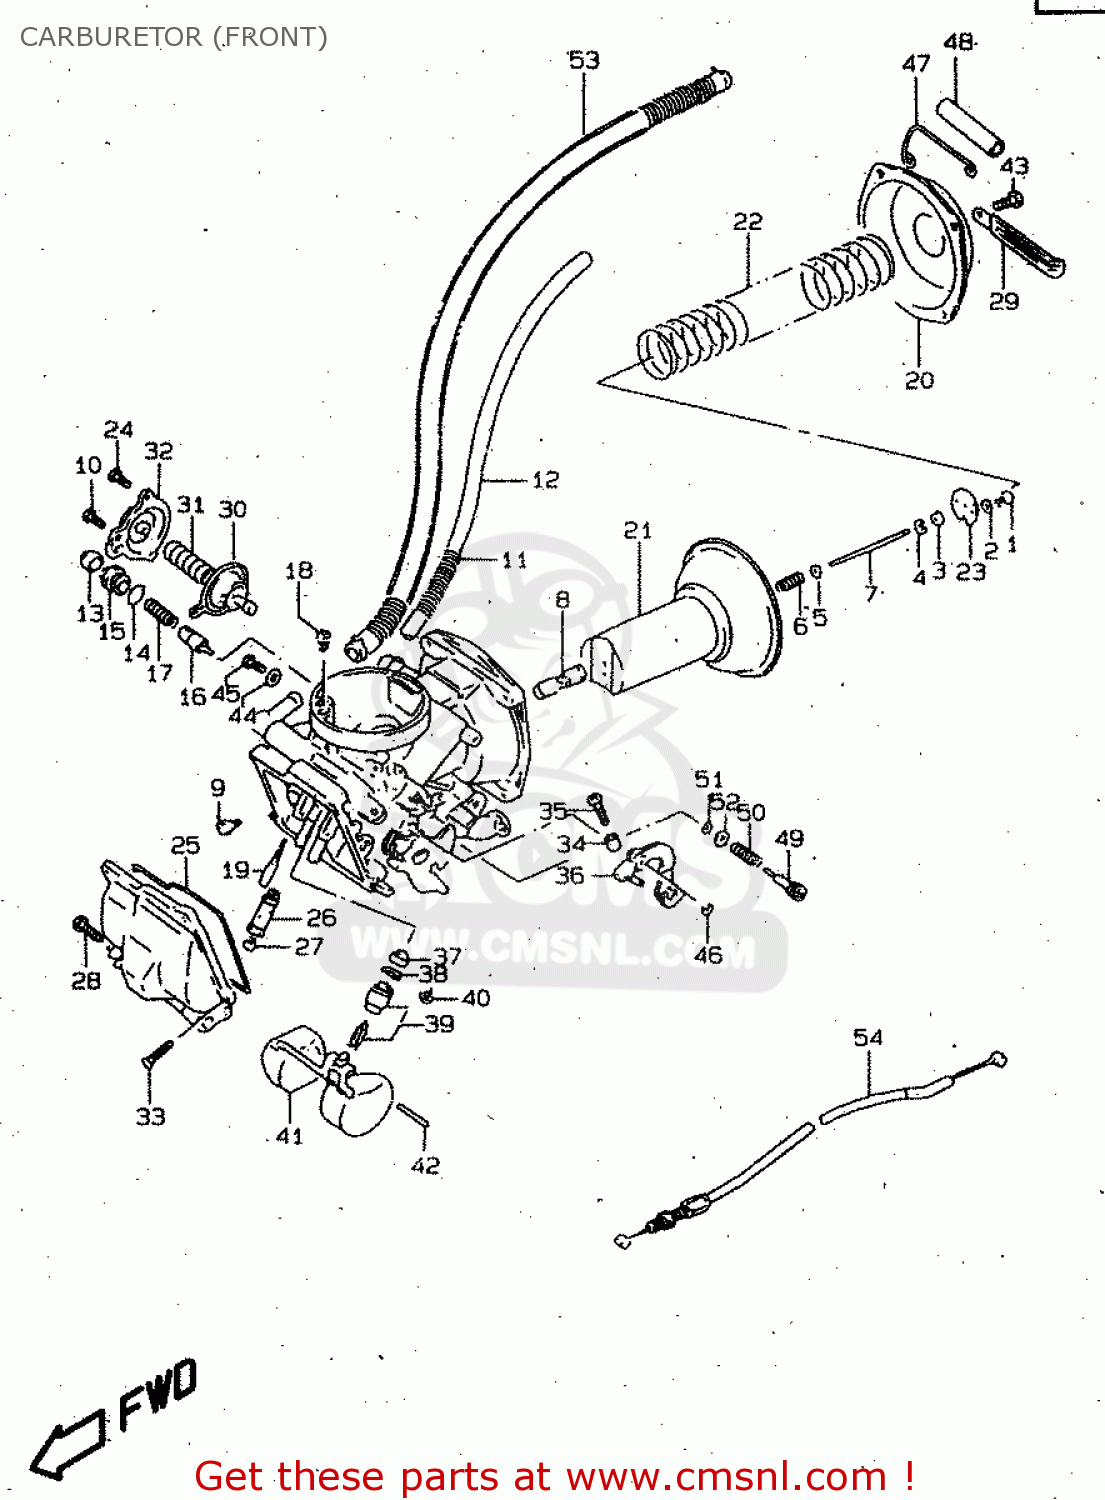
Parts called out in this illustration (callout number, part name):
1	SCREW
2	WASHER,LOCK
3	RING
4	CLIP
5	WASHER
6	SPRING
7	NEEDLE,JET
8	JET,NEEDLE(P-4)
9	SCREW
10	SCREW
11	SPRING
12	HOSE(5X8.2X600)
13	CAP
14	O RING
15	HOLDER,GUIDE
16	PLUNGER,STARTER
17	SPRING
18	JET,AIR(65)
19	JET,PILOT(40)
20	COVER
21	DIAPHRAGM ASSY
22	SPRING,DIAPHRAGM
23	PLATE
24	SCREW,UPPER
25	O RING,FLOAT CHAMBER
26	HOLDER,MAIN JET
27	JET,MAIN(95)
28	SCREW,DRAIN
29	CLAMP(L:65)
30	DIAPHRAGM ASSY
31	SPRING
32	COVER
33	SCREW
34	NUT
35	SCREW
36	LEVER ASSY
37	FILTER
38	O-RING,NEEDLE VALVE
39	VALVE ASSY,NEEDLE
40	SCREW
41	FLOAT
42	PIN,FLOAT
43	SCREW
44	GASKET,DRAIN PLUG (NAS)
45	SCREW(5X6)
46	E RING
47	CLIP
48	HOSE(6X10X600)
49	SCREW,PILOT
50	SPRING
51	O RING,PILOT AIR SCREW
52	WASHER
53	HOSE ASSEMBLY
54	CABLE,IDLE SYNCRO
